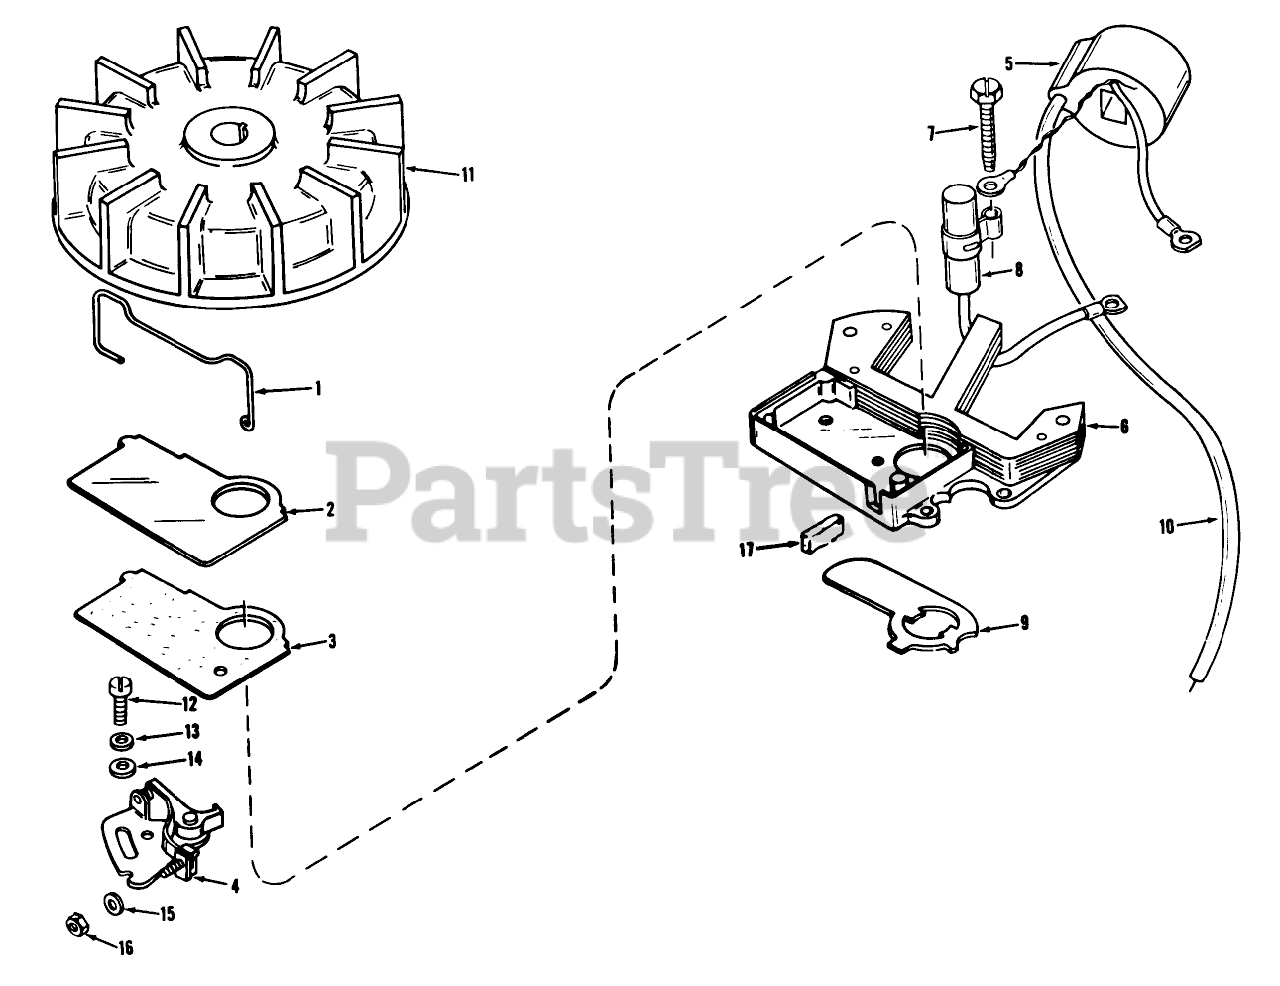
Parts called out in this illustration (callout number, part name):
1	Dust Cover Spring
2	Dust Cover
3	Dust Cover Gasket
4	Hose-Primer 209543
5	Coil Assy.
6	Gasket 209542
7	Condenser Screw
8	Condenser Assy.
9	Sealing Washer
10	STRAP S
11	RETAINER WASHER
12	Fuel Hose
13	Fuel Tank
14	Flatwasher
15	Washer
16	DECAL
17	Cam Felt
